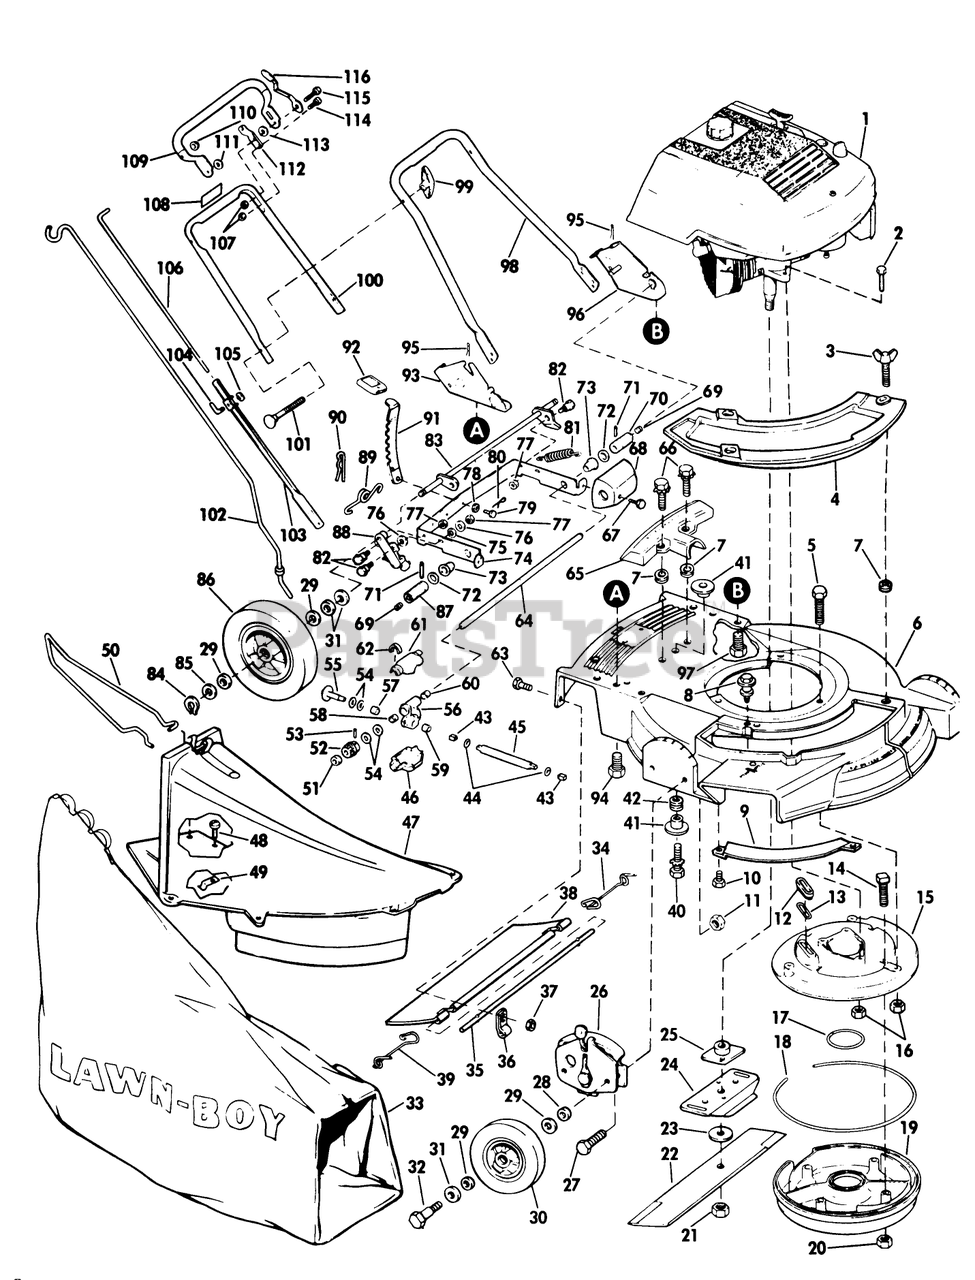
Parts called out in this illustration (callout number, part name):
2	BOLT F
3	WING SCREW LAWRE
5	SCREW V
9	BAR-TOE
11	NUT
12	SLEEVE
13	GASKET S
14	SCREW
16	NUT-LOCK F
18	Gasket Muffler (outside)
20	LOCKNUT E
21	NUT-BLADE
23	WASHER
25	PLATE AND COLLAR ASM
28	WASHER WROUGHT
29	WASHER
31	SPACER
32	BOLT WHEEL
33	ORD LB 89802 WHOLE GOODS
34	SPRIG T/SHLD ASOC
35	ROD 21" ADVANCE
36	CLAMP ROD KMC
39	SPRING;TRAILING SHIELD RH
41	SPACER ECK PRES
42	GROMMET
43	BUSHING
44	O Ring
51	WASHER
53	ROLL PIN
54	THRUST WASHER
57	NEEDLE BEARING
61	GEAR COVER UPPER
65	COVER
66	SCREW SEMS TRM HEX HD
68	GUARD
69	GREASE PLUG
71	PIN
76	WASHER S
77	STOP NUT
78	WASHER SPRING LAR
79	PIN
81	SPRING
82	BOLT RB&W
84	RET RING
85	SPACER
89	SPRING N.A.S
91	LEVER
92	KNOB
94	SCREW
95	HAIR PIN
97	SCREW
99	NUT-WING
100	HANDLE
102	ROD GRASSBAG
106	ROD CONTROL
111	WASHER M
115	BOLT RB&W
116	KNOB & SPRING
